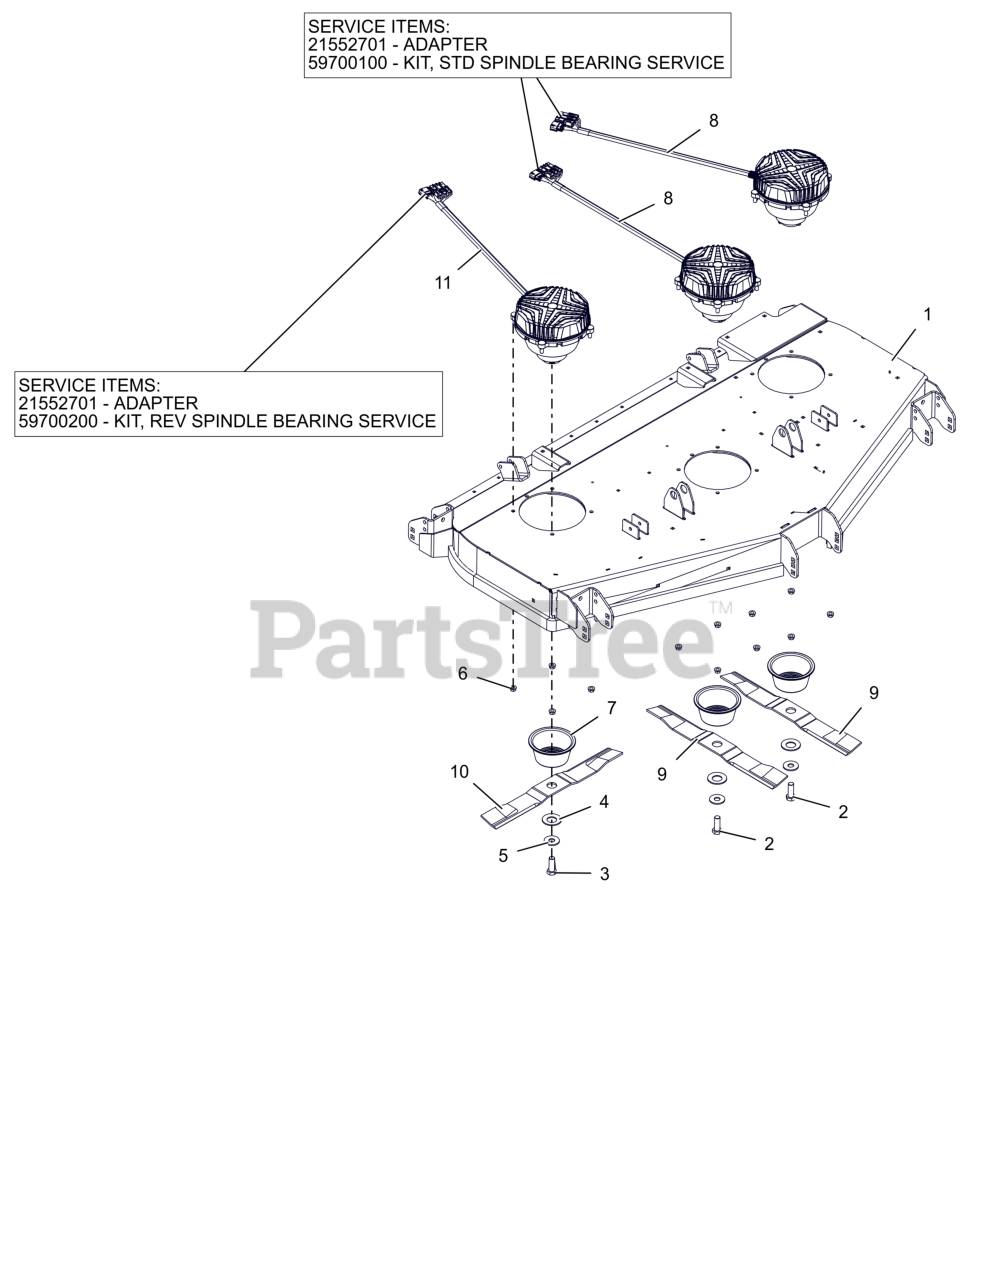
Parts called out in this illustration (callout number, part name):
1	WLDMT-60" PSEV REAR DISCH DECK
2	BLT, HEX .62-18X1.75 G8 ZCC
3	BLT, HEX 0.625-11X1.75 GR8 ZCC LH
4	WSHR, BLVL - .56X28.5X3 PHOS.COAT
5	WSHR, HRDN 0.687X1.75X0.134 HRD
6	NUT-LK-CTR-FLG .375-16 GF ZCC
7	GUARD, SPINDLE LOWER
8	MOTOR, SPINDLE-CW
9	BLADE, MOWER 20.5"
10	BLADE, MOWER - 20.5" EFF CCW
10	ADAPTER
10	KIT, STD SPINDLE BEARING SERVICE
11	MOTOR, DECK SPINDLE -CCW
11	ADAPTER
11	KIT,REV SPINDLE BEARING SERVICE
